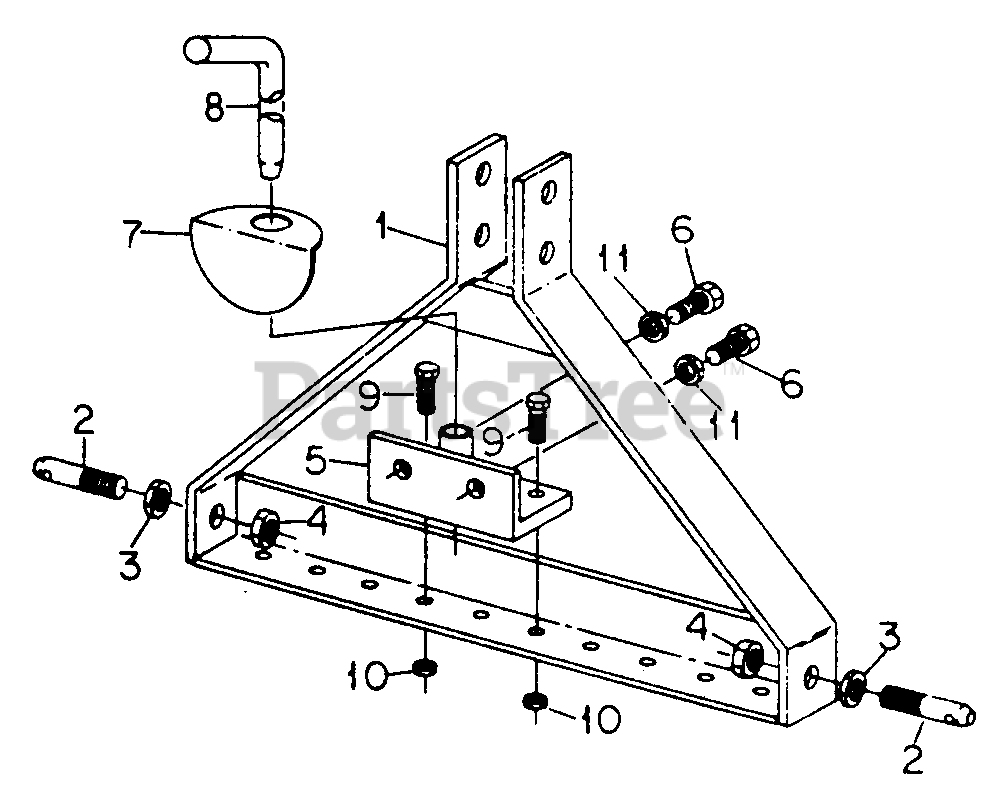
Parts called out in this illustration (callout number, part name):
1	Adapter Pkg, Frame Hitch
3	Nut, 5/8 Jam Type 5
5	Adapter, Sleeve
6	Bolt, 5/8 X 2 Type 5
7	Plate, Stabilizer
8	Pin, Sleeve
9	Bolt, 1/2 X 1-1/2 Type 5
10	Nut, 1/2 Type 5
11	Nut, 5/8 Jam Type 5
